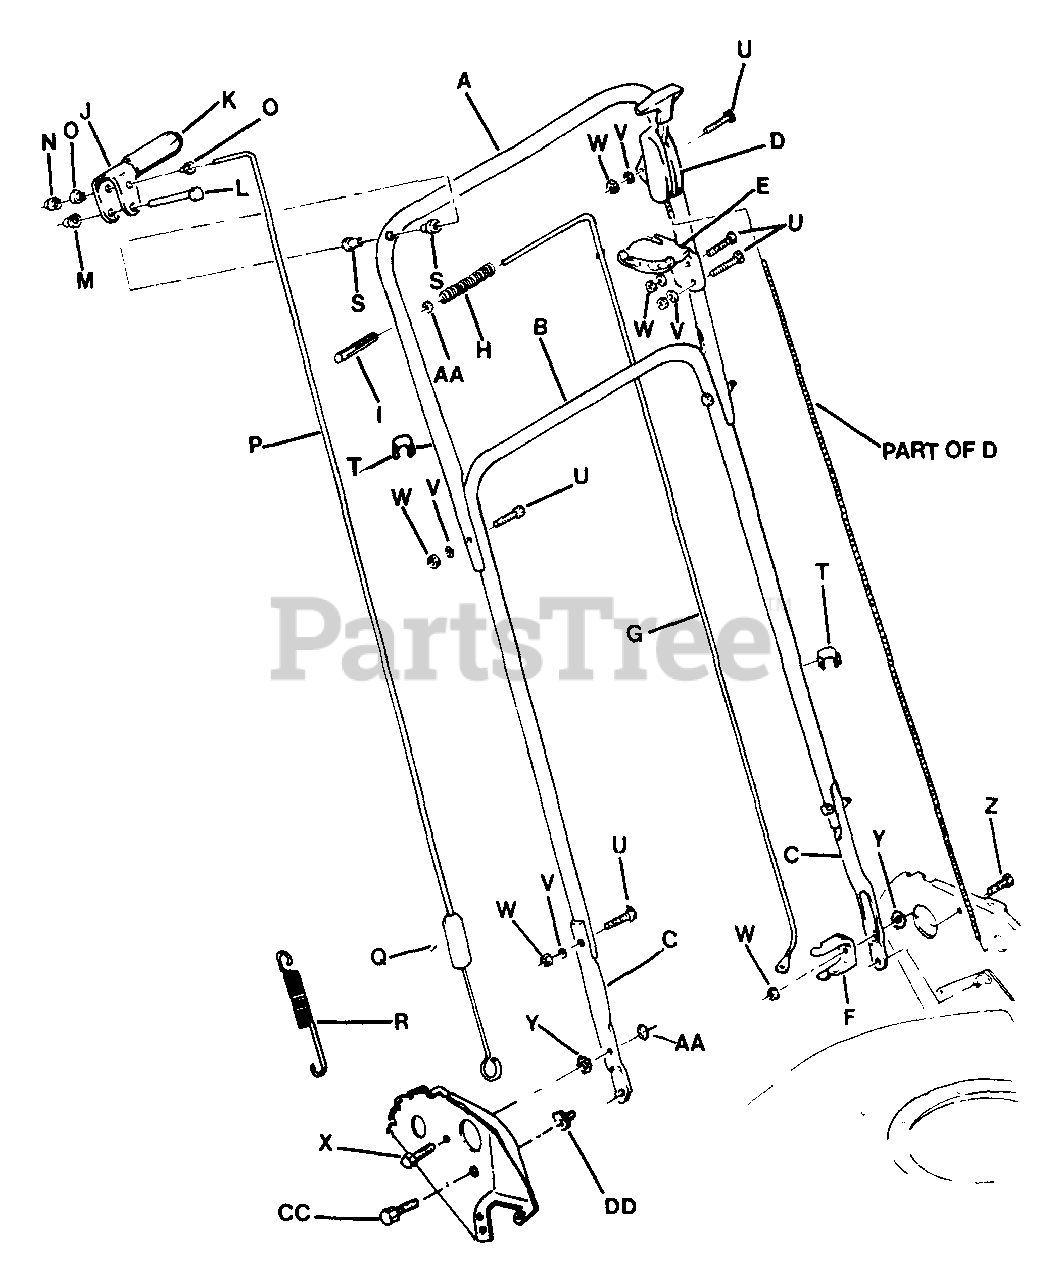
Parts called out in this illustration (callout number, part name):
A	HANDLE, UPPER
B	HANDLE, MIDDLE
C	HANDLE, LOWER
D	CONTROL, THROTTLE, 46.5" - B&S
D	CONTROL, THROTTLE, 42.5" - TEC
E	SECTOR, SPEED CONTROL
F	ANCHOR, Speed Control
G	LEVER, SPEED CONTROL 36"
H	SPRING, SPEED CONTROL LEVER
I	GRIP, SPEED CONTROL LEVER
J	HANDLE, Clutch
K	GRIP, CLUTCH HANDLE
L	PIN, CLUTCH HANDLE
M	NUT, PUSH 1/4
N	NUT, PUSH
O	BUSHING, PULL ROD (NYLON)
P	ROD, CLUTCH PULL
Q	COVER, VINYL
R	SPRING, CLUTCH
S	BUSHING, CLUTCH HANDLE PIN
T	CLIP
U	SCREW, HEX HEAD CAP 1/4-28 X 1 3/8
V	WASHER, INTERNAL TOOTH LOCK 1/4
W	NUT, HEX 1/4-28
X	SCREW, HEX HEAD CAP 5/16-24 X 1 1/4
Y	WASHER, INT/EXT TOOTH LOCK 5/16
Z	SCREW, HEX HEAD CAP 5/16-24 x 3/4
AA	WASHER, FLAT SAE 5/16
CC	SCREW, HEX HEAD CAP 5/16-18 x 5/8
DD	NUT, TEE 5/16-18
